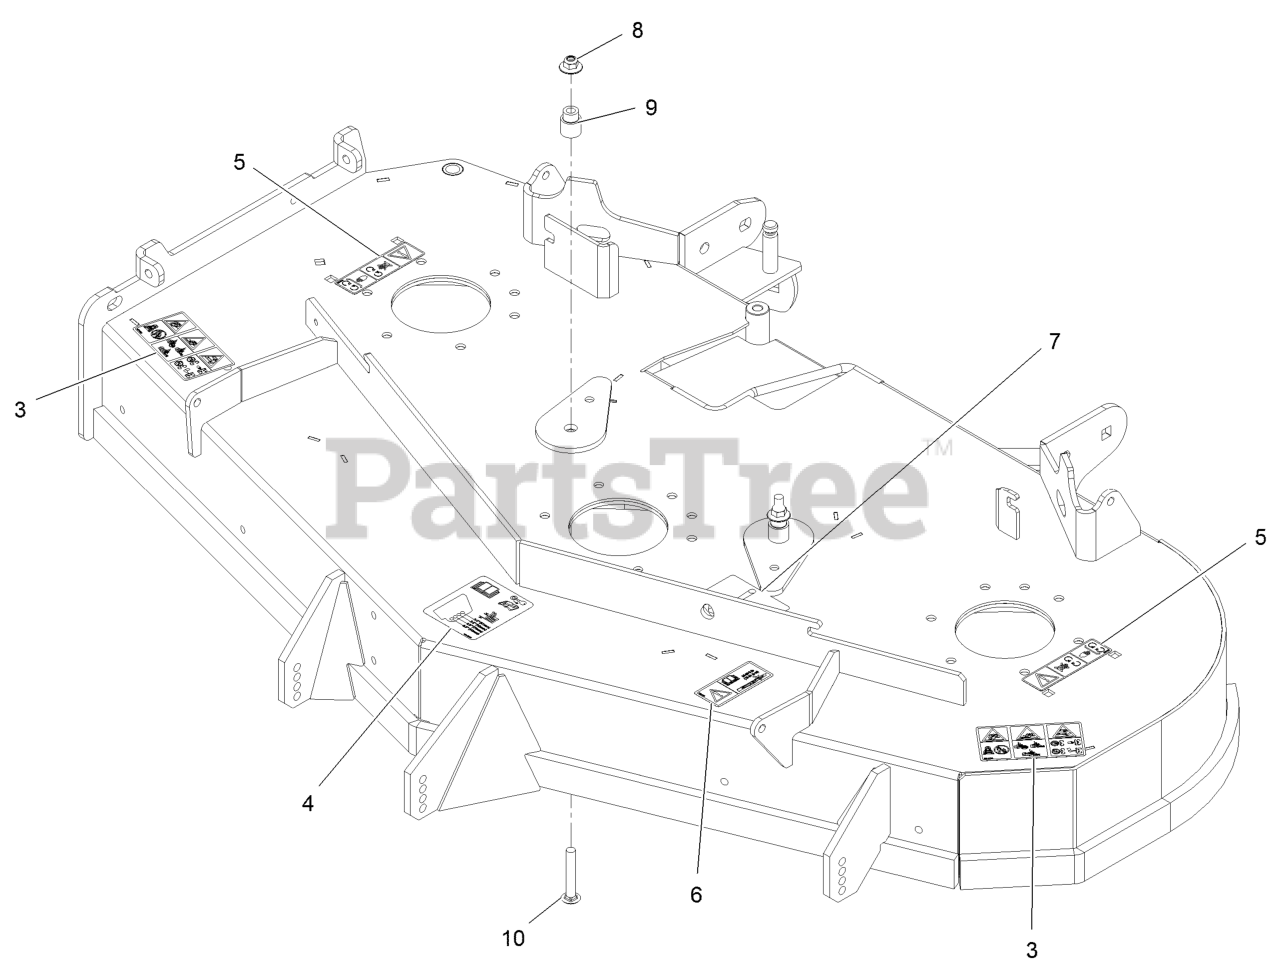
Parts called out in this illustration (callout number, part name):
3	DECAL-DANGER THROWN OBJECTS
4	DECAL-ROLLER, ANTI-SCALP
5	DECAL-COVER, MISSING
6	DECAL-BOLT TORQUE
7	DECAL-BELT ROUTING
8	Nut-Nyloc 3/8-16 Flg
9	BUSHING-IDLER
10	SCREW-CARR
